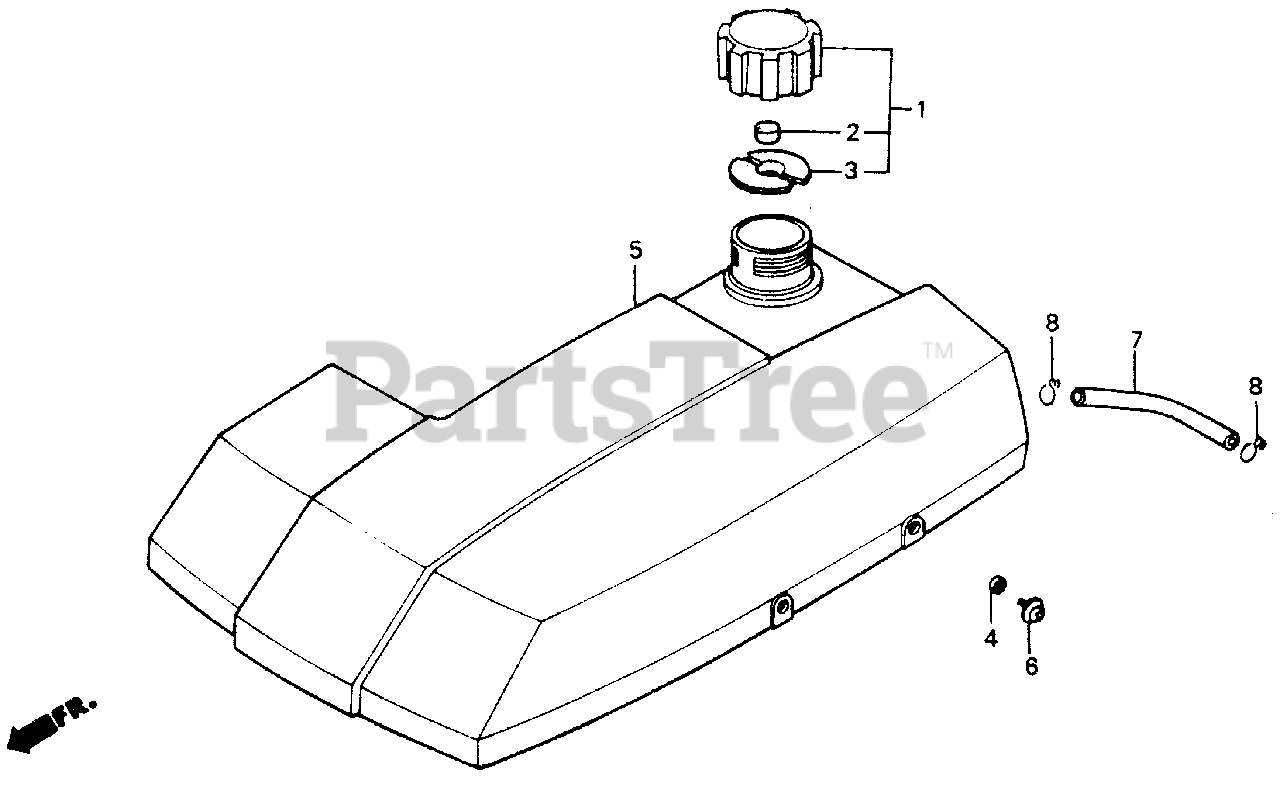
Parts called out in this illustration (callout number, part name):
1	CAP ASSY., FUEL TANK
2	SPONGE, FUEL CAP BREATHER
3	GASKET, FUEL CAP
4	COLLAR, FAN
5	COVER, ENGINE TOP (NOT AVAILABLE)
6	SCREW-WASHER (6X12)
7	BULK HOSE, FUEL (5.5X3000) (5.3X80)
8	CLIP, TUBE (B10)
